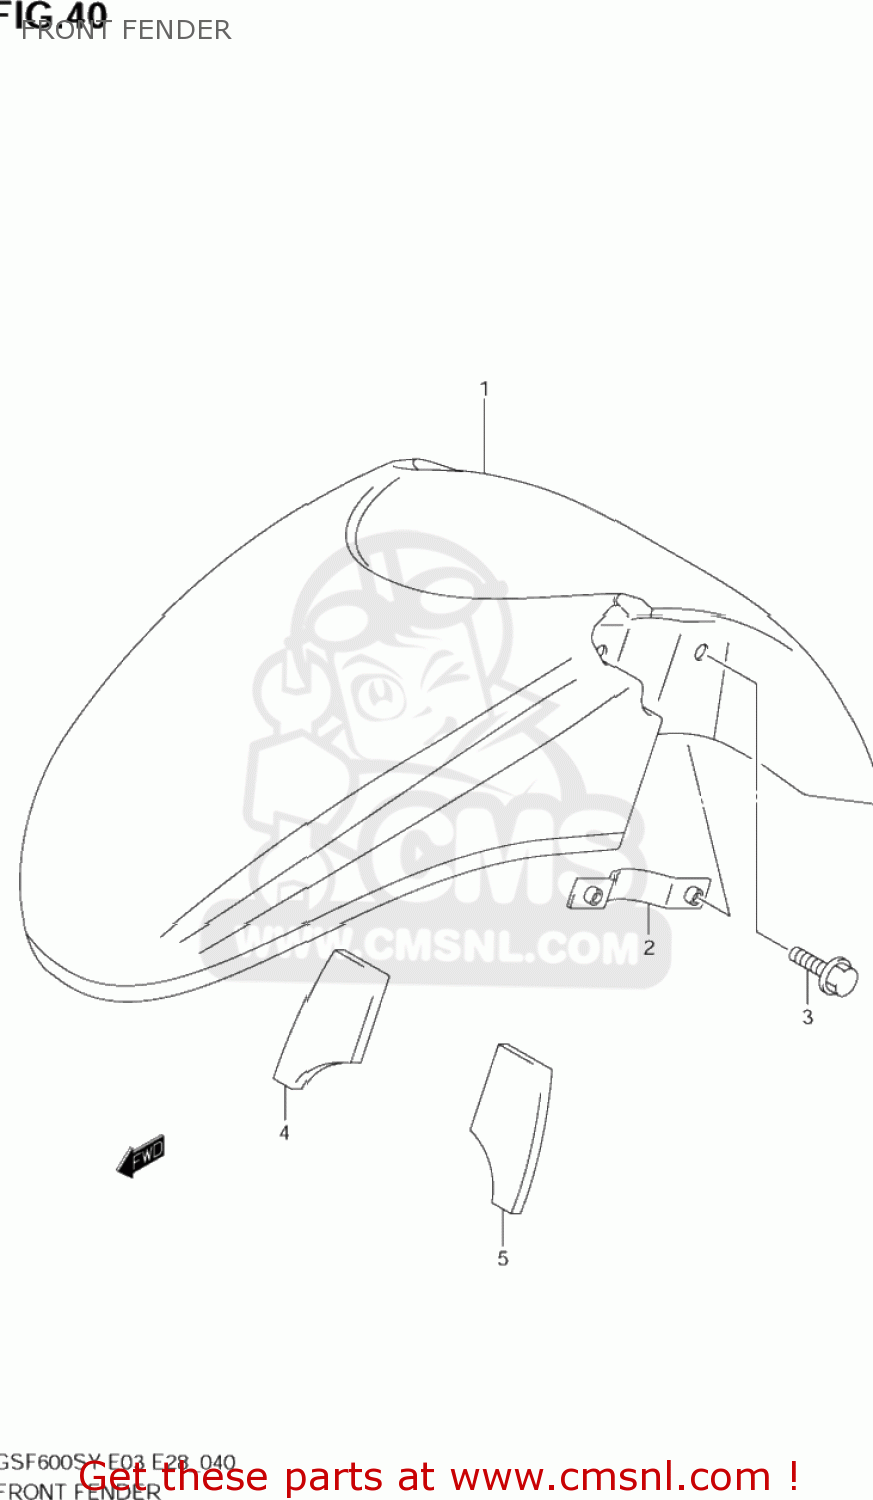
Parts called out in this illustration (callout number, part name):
1	FENDER,FR
2	PLATE,FR FENDER
3	BOLT
4	CUSHION,FR FENDER,R
5	CUSHION,FR FENDER,L
